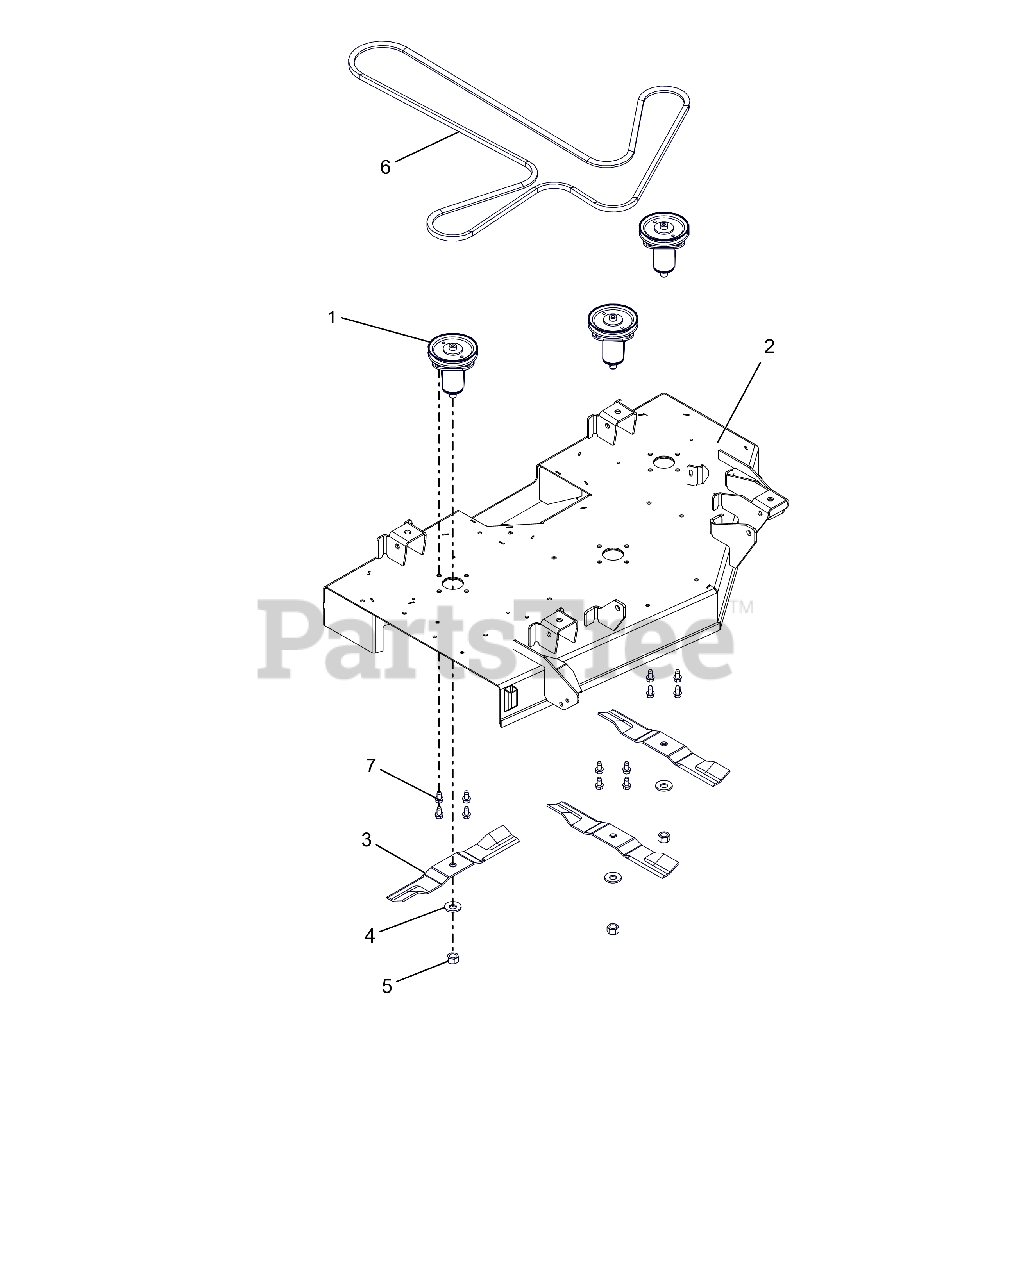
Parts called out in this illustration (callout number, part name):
1	KIT, DECK SPINDLE ASM-IKON-ZTX
2	KIT, 42" ARIENS DECK W/DECALS
3	BLADE, MOWER 15.00"
4	WSHR-BLVL .669X1.535X.138
5	NUT-STD .625-18 ZCC
6	V-BELT, 4L-WRAPPED
7	SCR,TAP .375-16X.75 HWH TR ZCC
